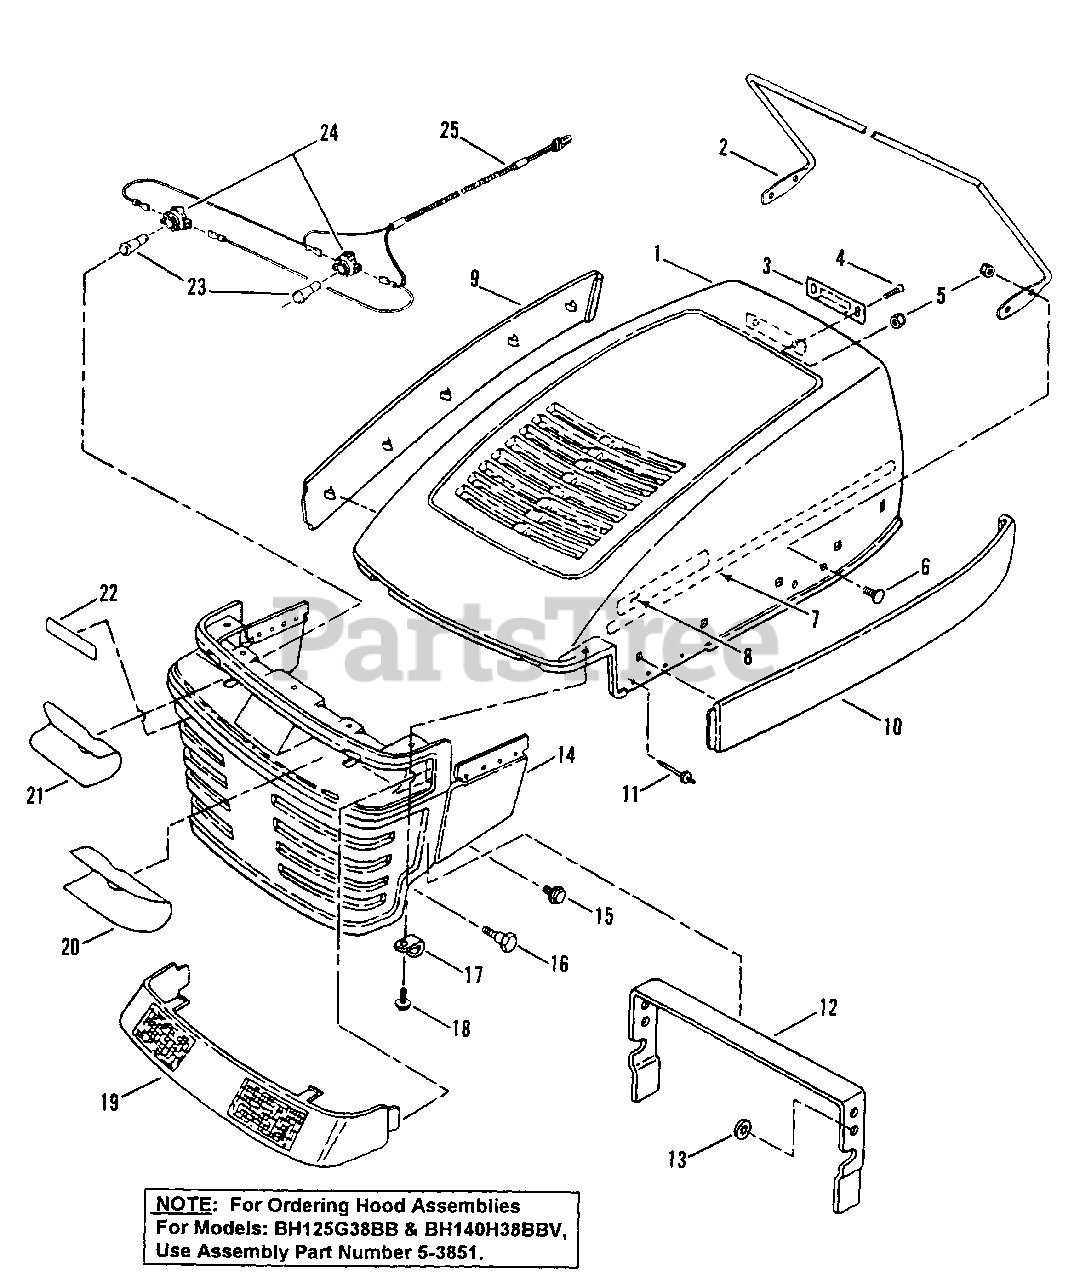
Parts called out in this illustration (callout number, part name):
1	HOOD, BLACKHAWK
2	ROD, Hood Support
3	LATCH, Spring
4	SCREW, 1/4-20 x 5/8" Truss Head, Torx
5	NUT, 1/4-20 Hex Nyloc
6	BOLT, 1/4-20 x 5/8" Flat Head Carriage
7	DECAL, Hood (Right Side)
7	DECAL, Hood (Left Side)
8	LOGO - BLACKHAWK
9	PANEL, Hood (Right Hand)
10	PANEL, Hood (Left Hand)
11	RIVET, 1/8" Pop
12	BRACE, Hood Support
13	RETAINER, Bolt
14	GRILLE, Hood
15	SCREW, 5/16-18 x 1/2" Hex Washer Head, Self-Tapping
16	BOLT, Shoulder, 3/8-16 x 1 1/4" Hex Socket, Torx
17	CLip, "J"
18	SCREW, M4.8 x 1.59 x 16.00MM, Special
19	LENS, Grille (Headlights)
20	DECAL, Reflect (Left Hand)
21	DECAL, Reflect (Right Hand)
22	LOGO - BLACKHAWK, 14HP Hydro Model BH140H38BBV
22	LOGO - BLACKHAWK, 12HP Gear Drive Model BH125G38BB
23	BULB, Headlights
24	SOCKET, Headlight Bulb
25	HARNESS, Headlight Wiring
